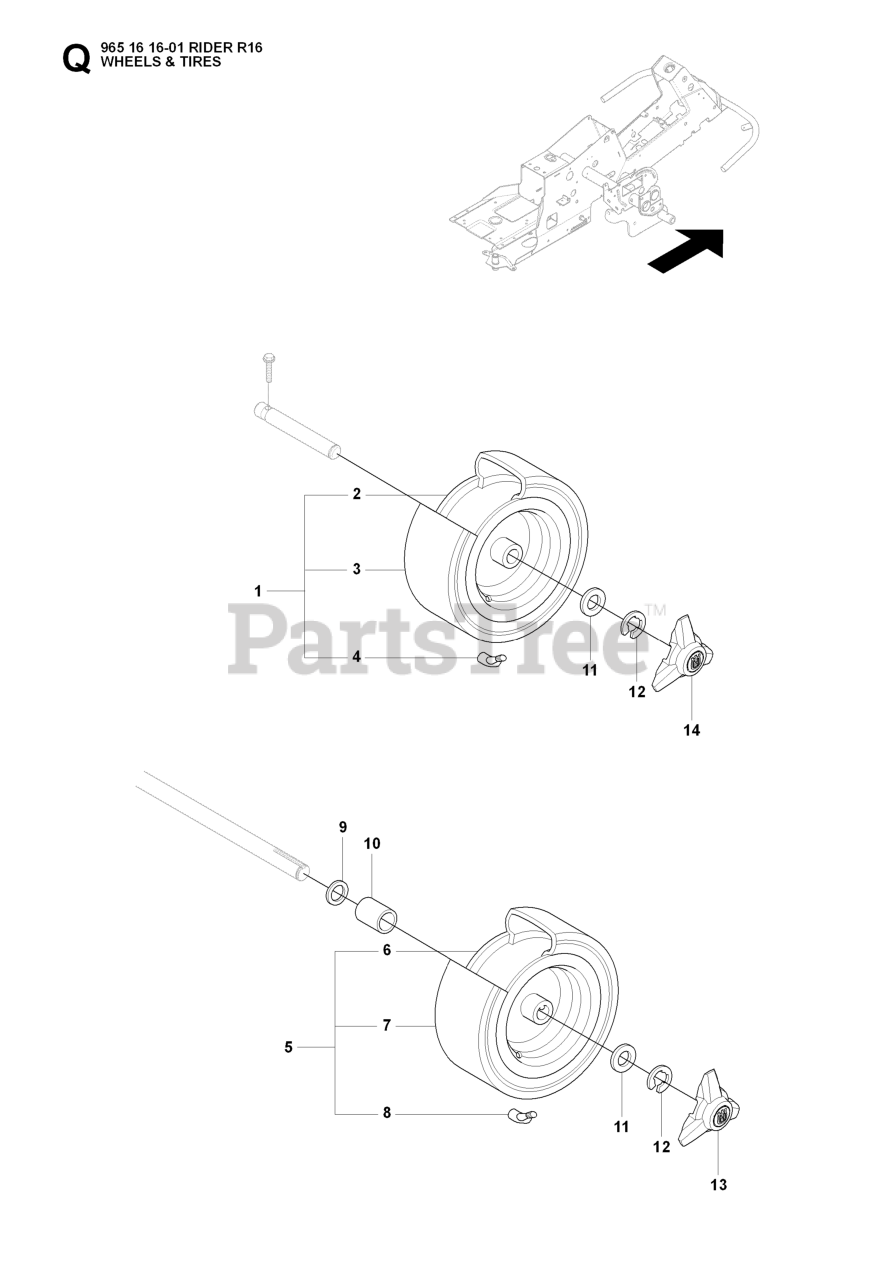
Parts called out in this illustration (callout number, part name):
5	WHEEL
6	RP RIM
10	SPACE SLEEVE
12	RETAINING RING
